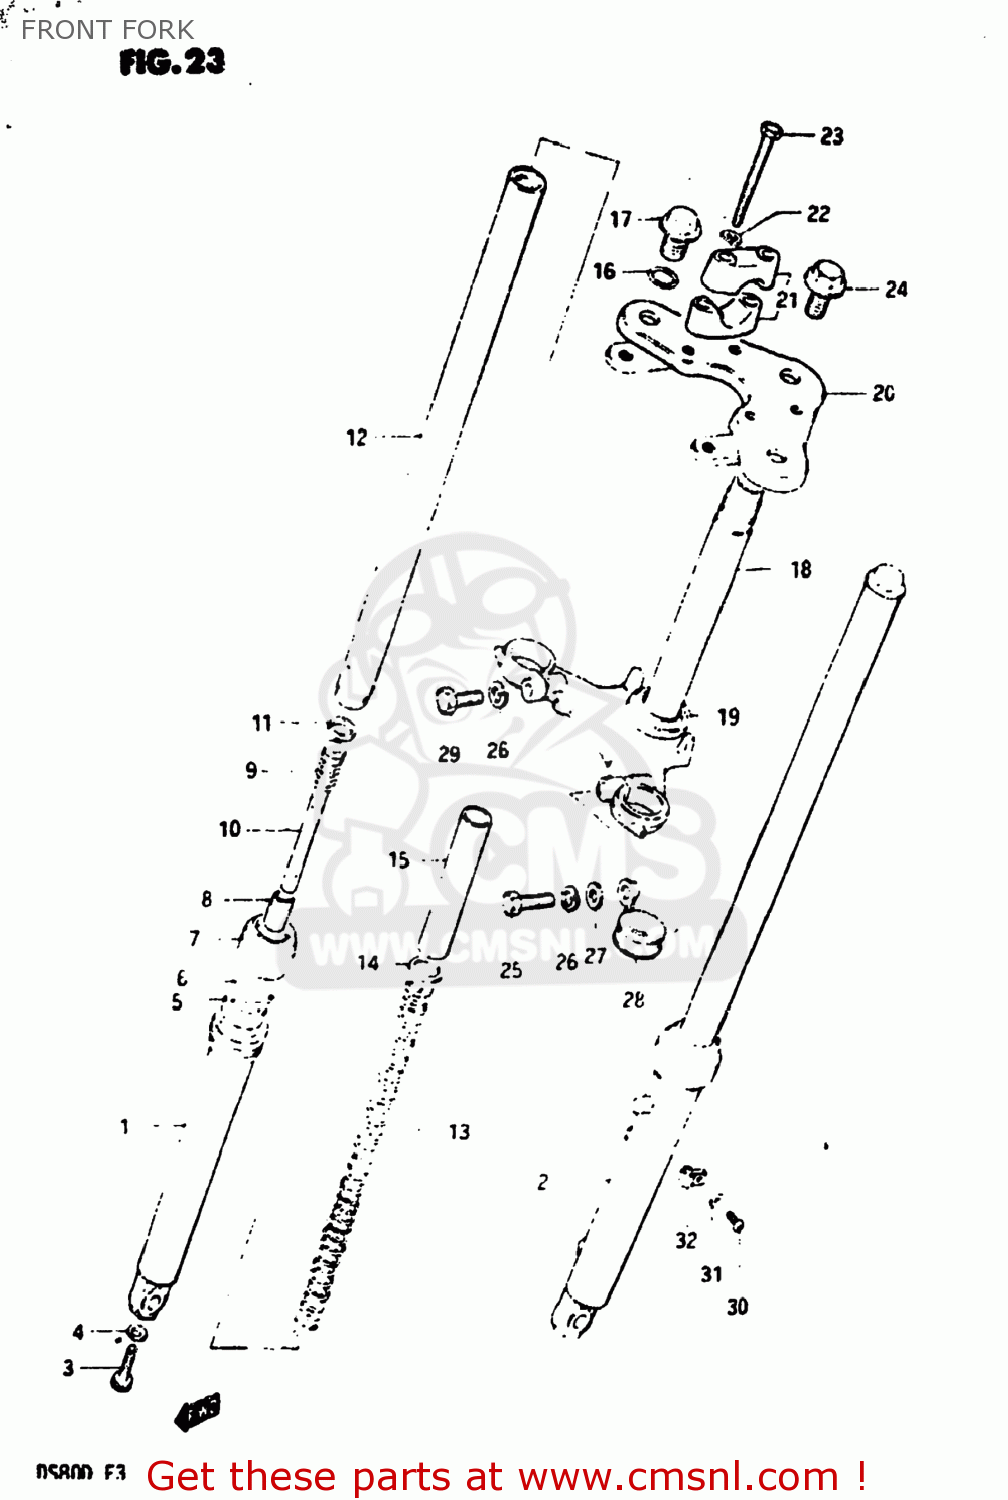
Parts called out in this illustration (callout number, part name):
1	TUBE,OUTER,RIGHT
2	TUBE,OUTER,LEFT
3	BOLT(8X27)
4	GASKET (NAS)
5	SEAL,OIL
6	CIRCLIP,FORK OIL SEAL
7	DUST SEAL
8	PIECE,OIL LOCK
9	SPRING,REBOUND
10	CYLINDER,FR FORK
11	RING,PISTON
12	TUBE,INNER
13	SPRING
14	JOINT,SPRING
15	SPACER,SPRING
16	O-RING,FORK INNER TUBE
17	CAP
18	STEM,STEERING
19	RACE,STEERING OUTER LWR
20	HEAD,STEERING STEM
21	HOLDER,HANDLE UPR
22	LOCK WASHER
23	BOLT 8X55
24	BOLT
25	BOLT,M10X1.25X
26	LOCK WASHER
27	WASHER
28	CLIP,CABLE
29	BOLT 10X30
30	SCREW
31	LOCK WASHER
32	CLIP,CABLE
